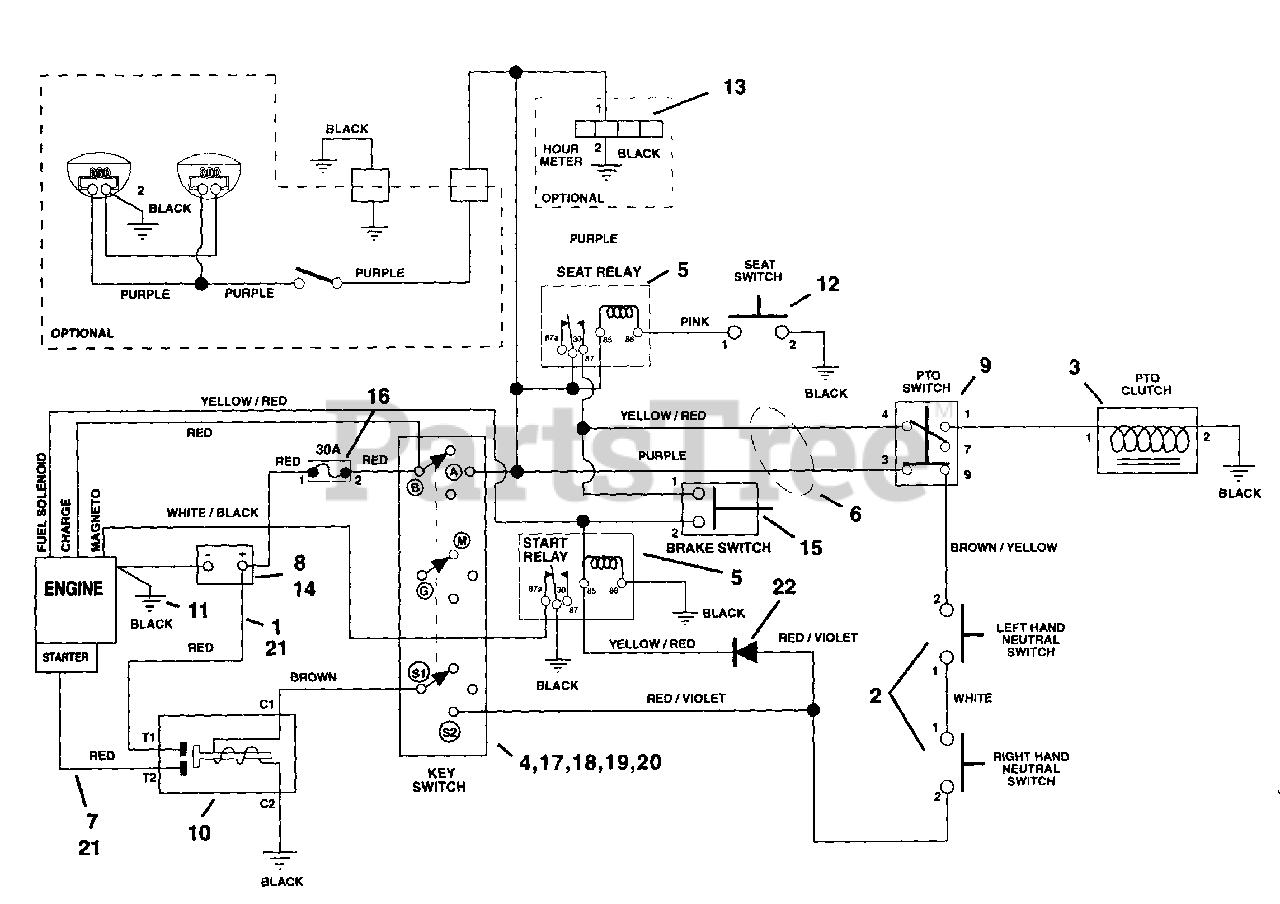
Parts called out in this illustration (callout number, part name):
1	CBL,BATTERY TO SOLENOID
2	SWITCH, NEUTRAL START N.O.
3	CLUTCH, ELECTRIC - WARNER
4	KEY SWITCH
5	RELAY
6	WIRE HARNESS 1540
7	START CABLE 22"
8	BATTERY W/ TUBE
9	SWITCH, CLUTCH WITH RETAINER
10	SOLENOID
11	GROUND CABLE .31X22.00X.31
12	SWITCH- SEAT
13	HOUR METER
14	RUBBER PAD
15	SWITCH- SINGLE POLE N.O.
16	7.5 AMP Fuse
17	KEY -W/CAP
18	CAP - IGNITION SWITCH
19	NUT- PANEL .562-24 GRECO
20	WSHR-LK-INT .563X.040 PL
21	BOOT, INSULATOR
22	MOLDED DIODE PLUG 1 AMP
